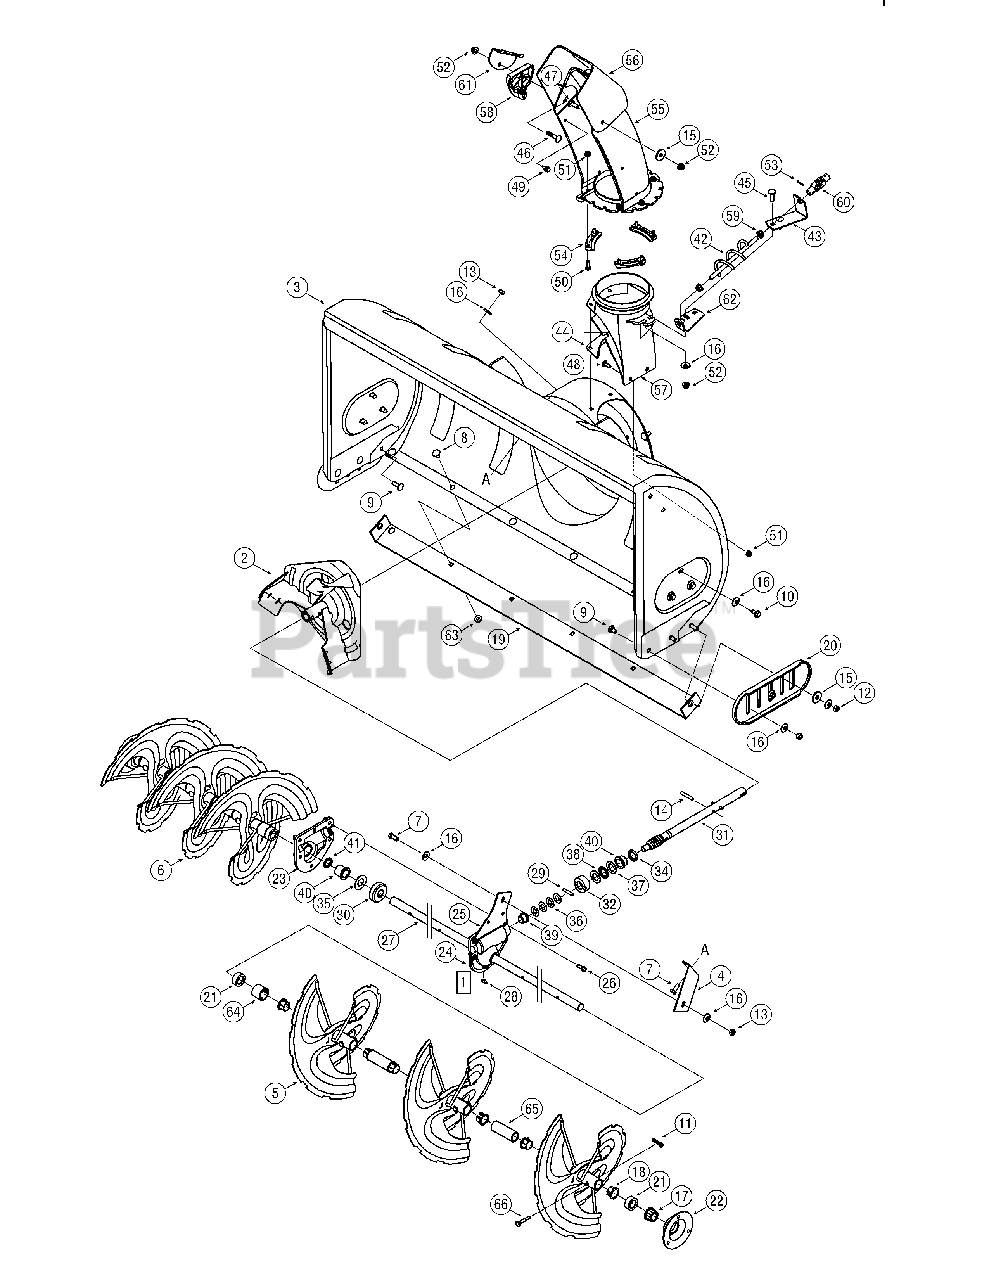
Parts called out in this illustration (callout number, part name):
1	Auger Gear Box (Incl. Ref. 23-41)
2	Impeller Assembly, 12"
3	Housing Assembly
4	Housing Brace Bracket
5	LH Spiral Auger
6	RH Spiral Auger
7	Hex Cap Screw, 5/16-24 x .75
8	Carriage Bolt, 5/16-18 x .62
9	Splined Carriage Screw
10	Self Tapping Screw
11	Bow-Tie Cotter Pin
12	Hex Nut, 5/16-18
13	Hex Nut, 5/16-24
14	Spirol Pin, 1/4 x 1-1/2
15	Flat Washer, .344 x 1.125 x .12
16	Bell Washer, .340 x .872
17	Hex Flange Bearing, .75 ID
18	Flange Bushing, .80 x .91
19	Skid Plate Bracket, 42"
20	Slide Shoe
21	Spacer, .75 x .125 x .5
22	Hex Bearing Housing, 1.0
23	RH Reducer Housing
24	LH Reducer Housing
25	Housing Brace Plate
26	Self Tapping Screw, 1/4-20 x .75
27	Spiral Axle, 41.5"
28	Hi-Pro Key, 3/16 x 5/8
29	Spring Spirol Pin, .25 x 1.25
30	Worm Gear, 20-tooth
31	Worm Shaft
32	Thrust Collar
34	Grease Seal
35	Flat Washer, .76 x 1.5 x .030
36	Flat Washer, .508 x 1.0 x .020
37	Thrust Washer, .75 x 1.25 x .0615
38	Thrust Bearing, .75 x 1.25 x .078
39	Flange Bearing, .503 x .75
40	Flange Bearing, .75 x 1.0 x .59
41	Grease Seal
42	Chute Crank Assembly
43	Chute Crank Bracket
44	Chute Reinforcer
45	Splined Carriage Screw
46	Carriage Bolt, 5/16-18 x 1.5
47	Carriage Screw, 5/16-18 x 1.0
48	Screw, 1/4-20 x .75
49	Hex Index Washer Screw
50	Hex Cap Screw, 1/4-20 x .75
51	Nylon Hex Lock Nut, 1/4-20
52	Nylon Hex Lock Nut, 5/16-18
53	Spirol Pin, .125 x .82
54	Chute Flange Keeper
55	Lower Chute
56	Upper Chute
57	Adapter Chute
58	Chute Tilt Cable Guide
59	Plastic Bushing
60	Joint Block Assembly
61	Cable Bracket
62	Chute Crank Bracket
63	Flange Lock Nut, 5/16-18
64	Spacer 1.25 x .75 x 1.00
65	Sleeve .758 x 1.00 x 2.70
66	Shear Pin, .25 x 1.50
